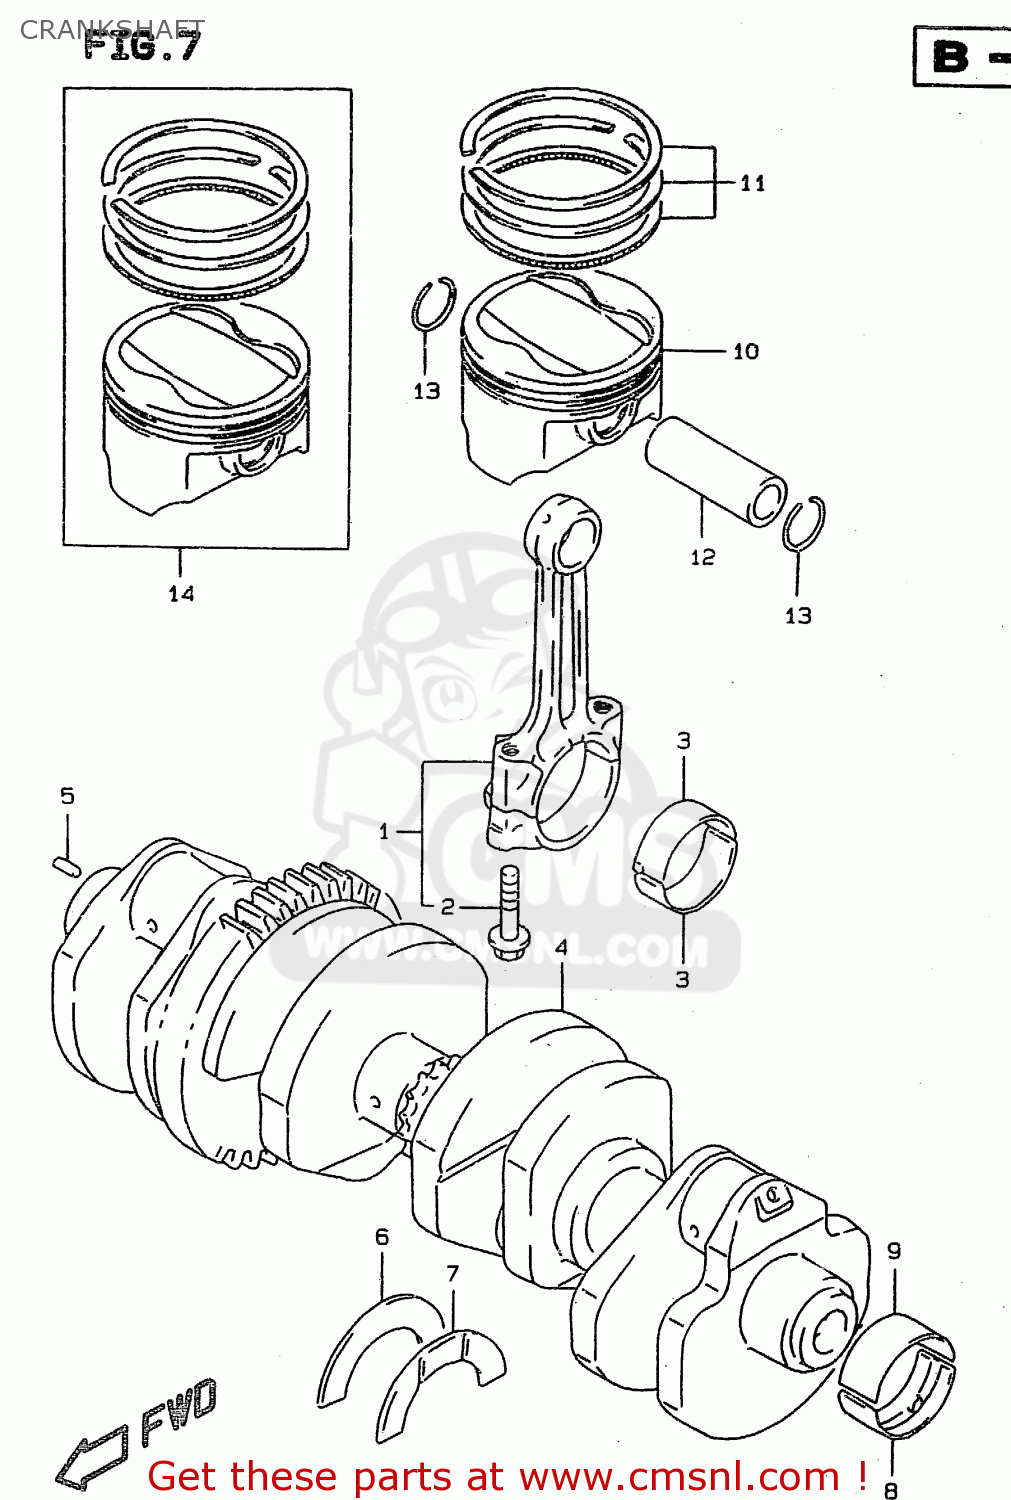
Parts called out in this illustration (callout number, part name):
1	CONNECTING ROD ASSY
2	BOLT,CONNCTING ROD
3	BEARING,CRANK PIN
4	CRANKSHAFT SET
5	PIN
6	BEARING,CRANK THRUST(GREEN)
7	BEARING,CRANK THRUST(RED)
8	BEARING,CRANKSHAFT LWR
9	BEARING,CRANKSHAFT UPR
10	PISTON (73.00MM)
11	RING SET,PISTON
12	PIN,PISTON
13	RING,SNAP
14	PISTON SET(OS:0.5)
